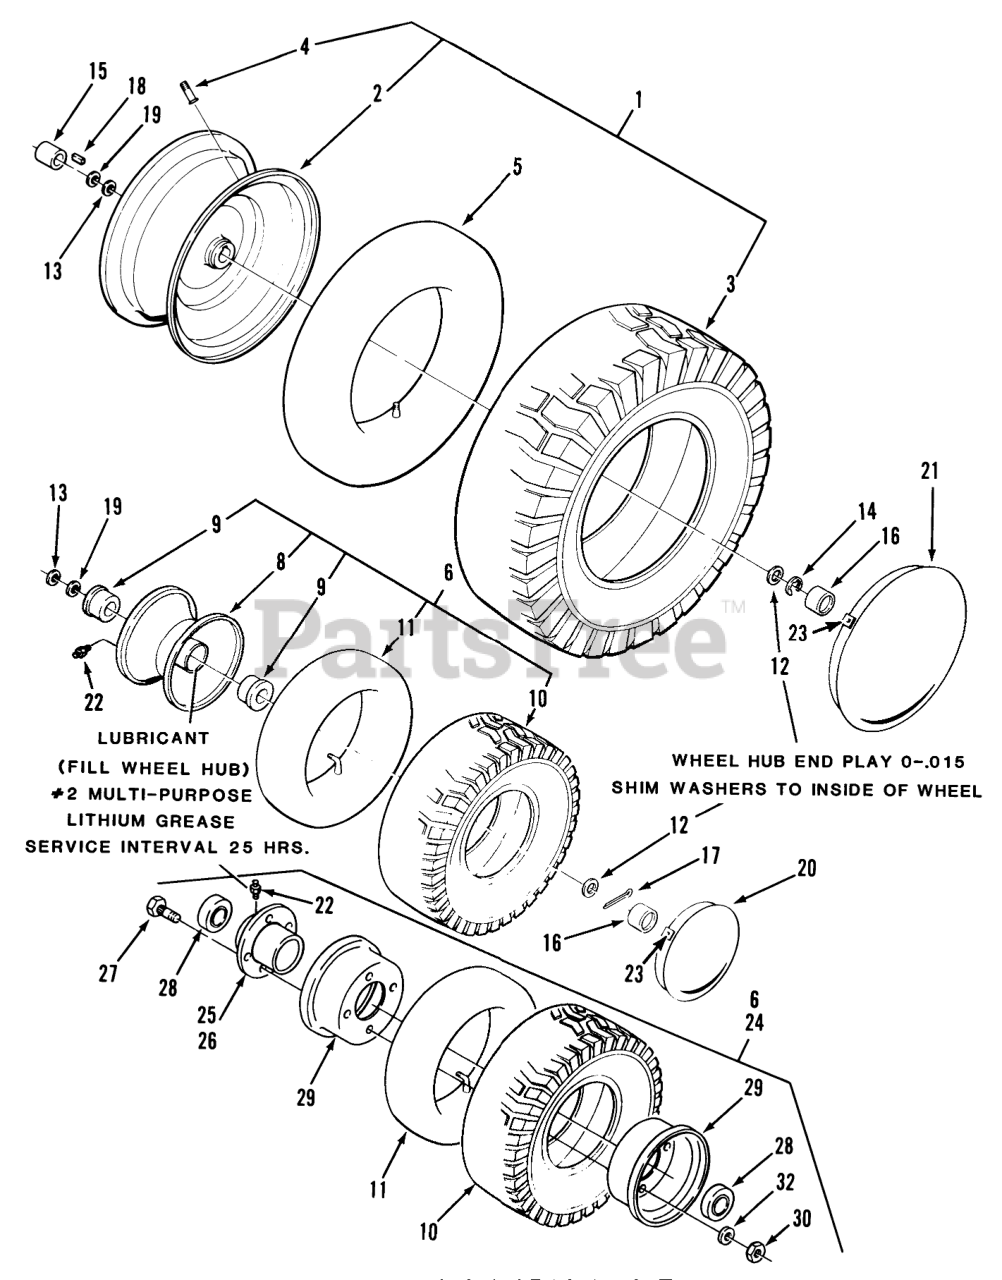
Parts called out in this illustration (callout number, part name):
1	Rear Wheel and Tire 108-4 Only
2	Rear Wheel 108-4 Only
3	Rear Tire 16 x 6.50-8 108-3 Only
4	VALVE
5	TUBE-INNER
6	ASSY WHEEL & TIRE
8	Frt Wheel w/Bushings & Grease Fitting 108-4
9	BEARING-WHEEL
10	Tire 4.10 x 3.50-4 108-3 Only
12	WASHER-FLAT
13	WASHER
14	E Ring
15	LH AXLE SPACER
16	HUB CAP-FLAT BLACK
17	Cotter Pin
18	SQ KEY
19	WASHER-SHIM
20	4IN HUBCAP W/LOGO
21	8" HUB CAP WITH LOGO
22	ZERK-GREASE
23	SPRING CLIP
24	Front Wheel Complete (Silver) 112-C Only (includes items 22, 25, 29, 30, 31 & 32) 112-C
25	Inner Hub (includes items 22, 26, 27 & 28) 112-C.
26	HUB-INNER
27	Stud 112-C Only
28	BEARING-WHEEL
30	NUT-6
31	LOCKWASHER
